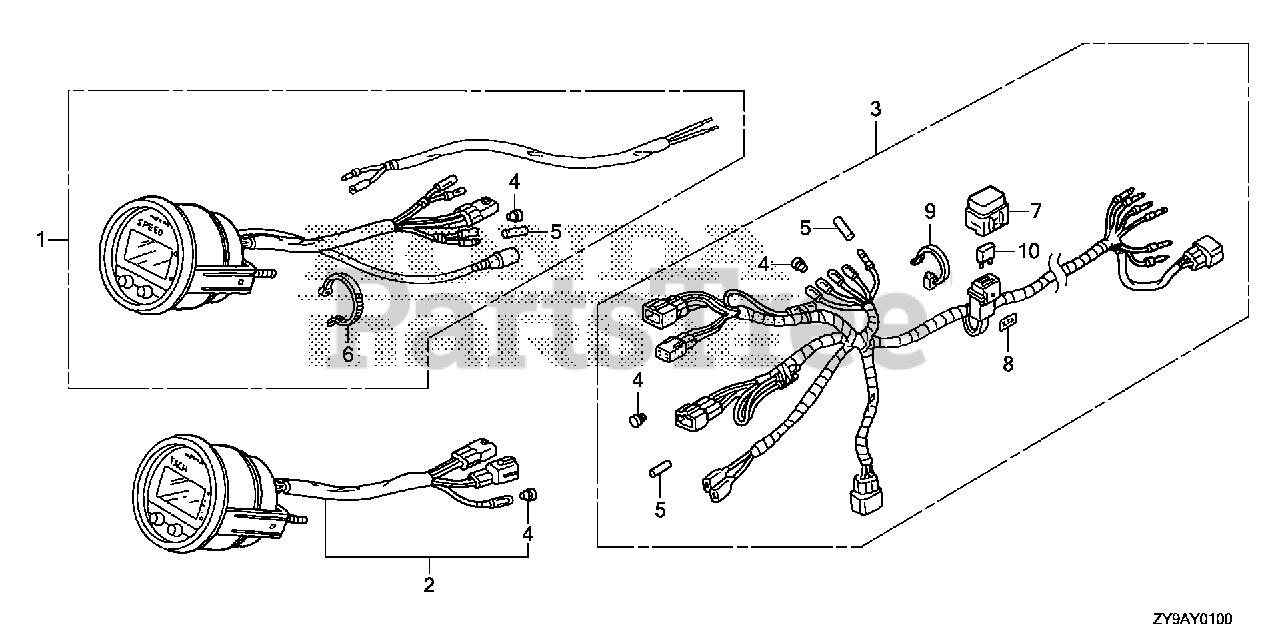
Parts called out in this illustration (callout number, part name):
1	SPEEDOMETER KIT (DIGITAL)(USA) (NOT AVAILABLE)
2	METER KIT, TACHO (DIGITAL) (USE FOR 32540-ZY3-800/801)
3	HARNESS ASSY., METER (A)(DIGITAL)
4	PLUG, CONNECTOR (INNER) (TROLLING CONTROL)
5	PLUG, CONNECTOR (OUTER) (ENGINE NO.)
6	BAND (BLACK 3.5X140)
7	COVER ASSY., FUSE (7.5A)
8	MARK, FUSE (7.5A)
9	TIE, CABLE
10	FUSE, BLADE (7.5A)
